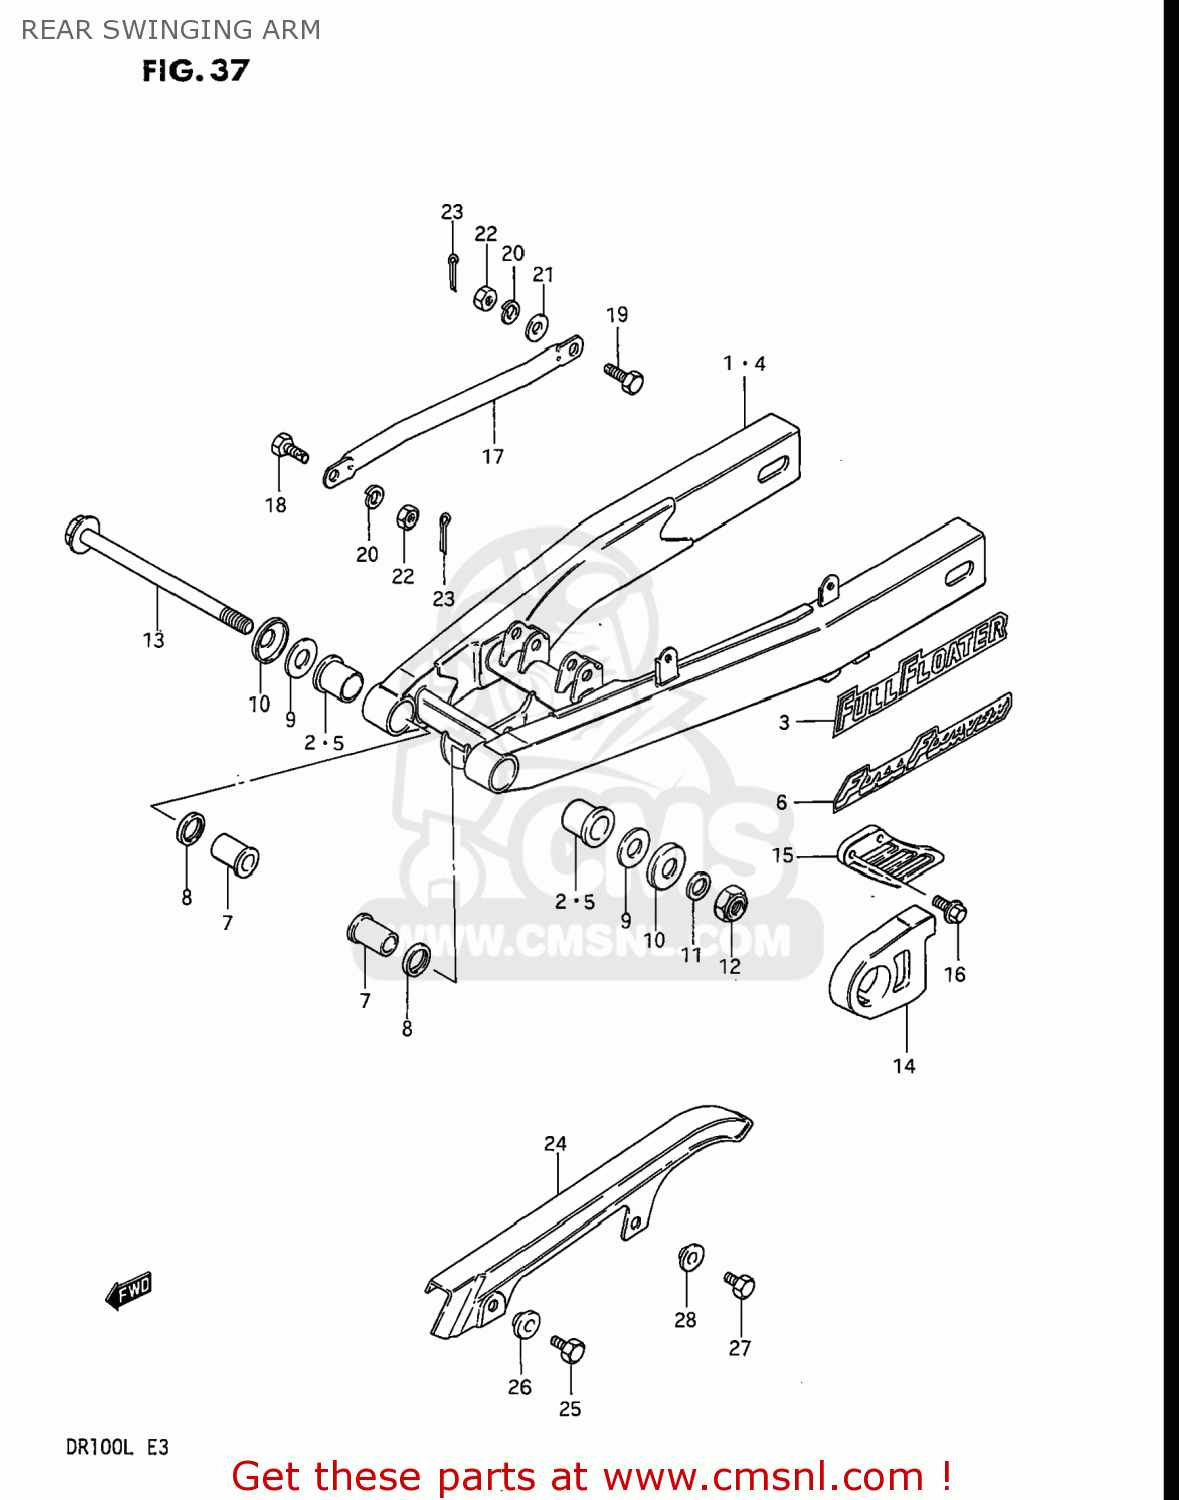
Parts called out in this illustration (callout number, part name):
1	SWING ARM ASSEMBLY,REAR
2	BUSH,RR SWINGING ARM PIVOT
3	EMBLEM
4	SWING ARM ASSEMBLY,REAR
5	BUSH,RR SWINGING ARM PIVOT
7	SPACER,RR SWGARM PIVOT
8	SEAL,OIL(20X27X5)
9	WASHER
10	CVR,RR SWGARM DUST SEAL(OD:40)
11	WASHER
12	NUT 14MM
13	SHAFT,REAR SWING ARM
14	BUFFER,CHAIN TOUCH DEFLECTOR
15	GUIDE,CHAIN
16	BOLT
17	TORQUE LINK,RR
18	BOLT(8X22)
19	BOLT(8X26.5)
20	LOCK WASHER
21	WASHER
22	NUT
23	PIN 20X20
24	CASE,CHAIN
25	BOLT 6X8
26	WASHER
27	BOLT
28	WASHER
